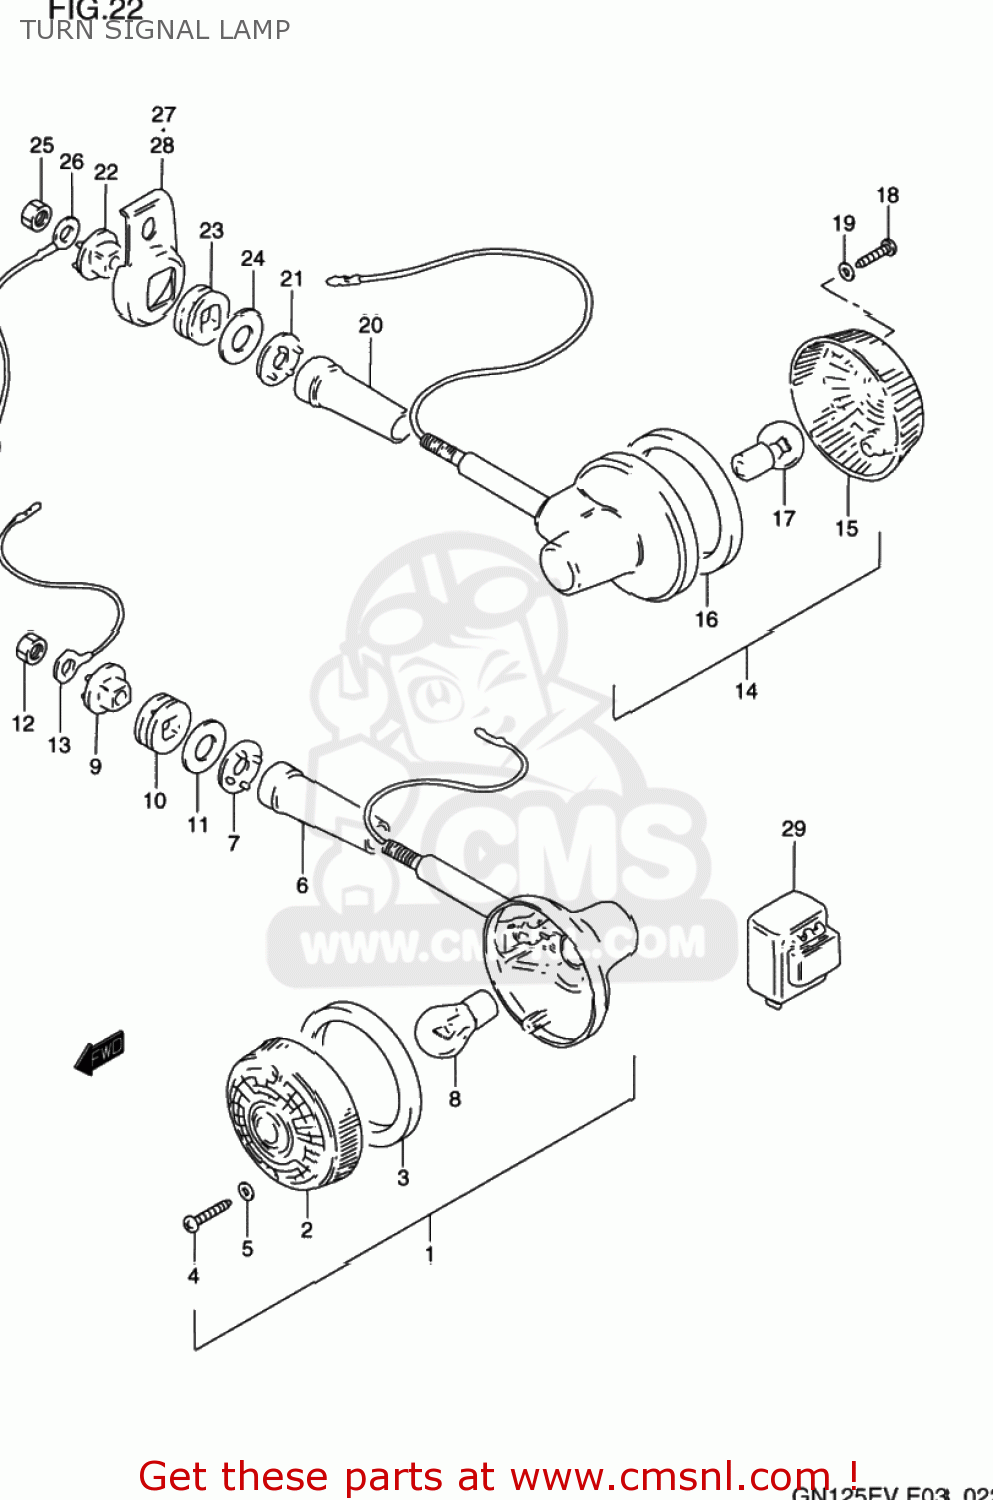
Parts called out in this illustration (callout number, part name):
1	LAMP ASSY,TURNSIGNAL
2	LENS
3	GASKET (NAS)
4	SCREW
5	GASKET (NAS)
6	COVER,STAY
7	CUSHION
8	BULB(12V23W,STANLEY,A4577A)
9	SPACER
10	CUSHION
11	WASHER (10.5X30X2.3)
12	NUT
13	LEAD WIRE,EARTH
14	LAMP ASSY,RR TURNSIGNAL
15	LENS
16	GASKET (NAS)
17	BULB(12V23W,STANLEY,A4577A)
18	SCREW
19	GASKET (NAS)
20	COVER
21	CUSHION
22	SPACER
23	CUSHION
24	WASHER (10.5X30X2.3)
25	NUT
26	LEAD WIRE,EARTH
27	BRACKET,RR TURNSIGNAL LAMP,R
28	BRACKET,RR TURNSIGNAL LAMP,L
29	RELAY ASSY,TURNSIGNAL
